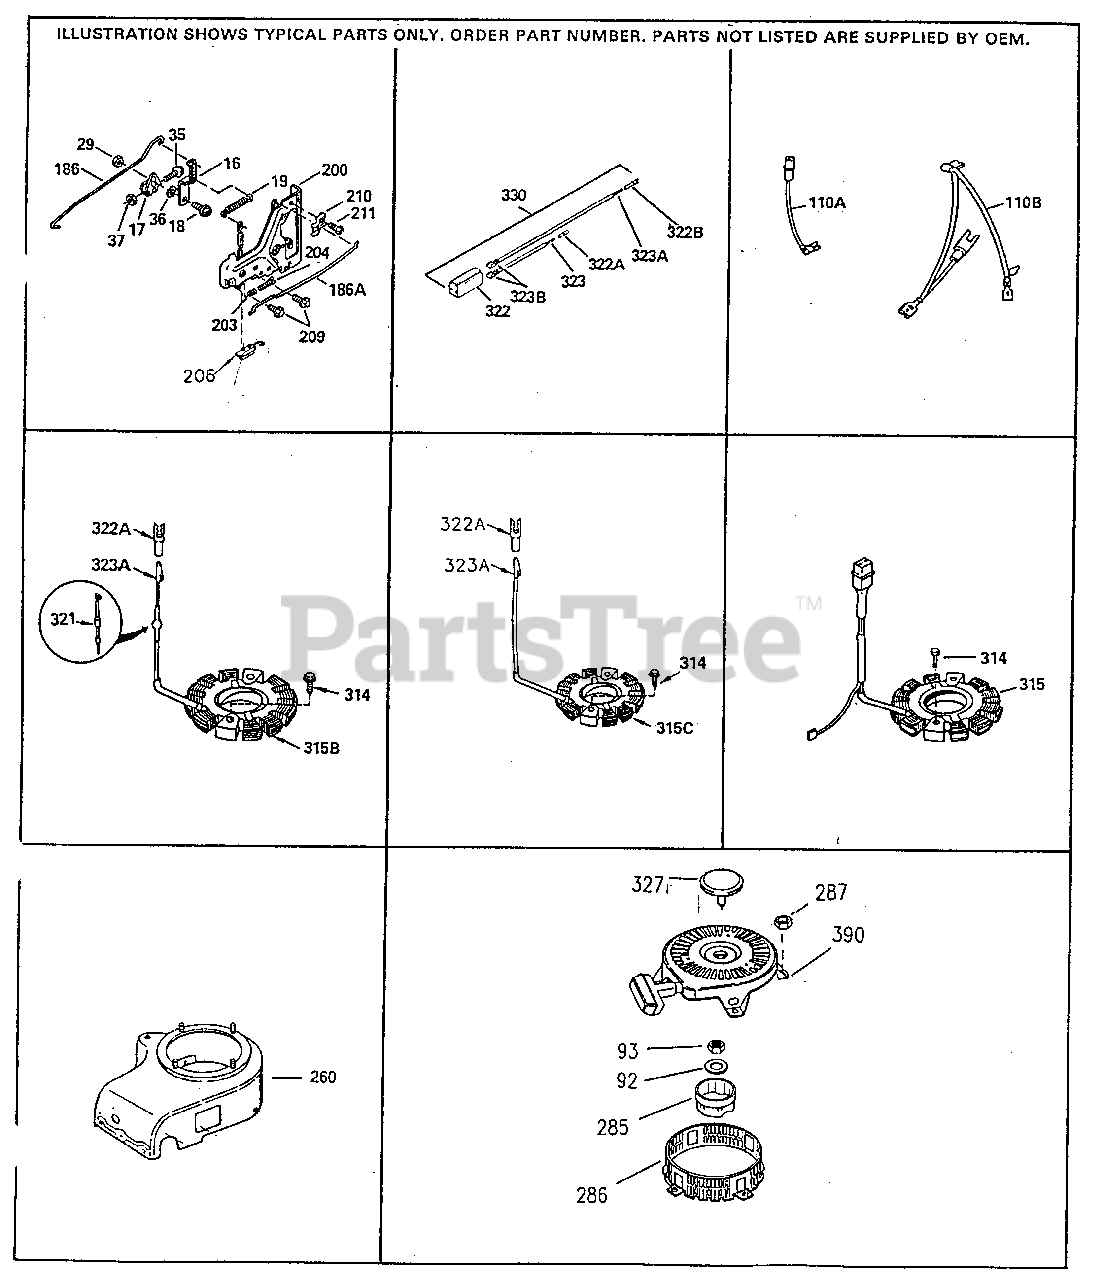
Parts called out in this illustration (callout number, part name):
16	Governor Lever (Incl. 212A)
17	Governor Lever Clamp
18	Screw, 8-32 x 5/16"
19	Extension Spring
28	Lock Nut, 8-32
35	Screw, 10-32 x 3/4"
36	Lock Washer #8
37	Lock Nut, 10-32
92	Lock Washer
93	Flywheel Nut
186	Governor Link
186A	Choke Link
200	Control Bracket (Incl. 203 & 204)
203	Compression Spring
204	Screw, 6-32 x 21/32"
209	Screw, 10-32 x 7/16"
210	Conduit Clip
211	Screw, 10-32 x 3/8"
238	Screw, 10-32 x 5-1/4"
245A	Pre-Cleaner Air Filter also available in Packaged Part #740015B
260	Blower Housing
261	Screw, T-30, 1/4-20 x 1/2"
262A	Screw, 5/16-24 x 25/32"
264A	Screw, T-30, 1/4-20 x 1/2"
286	Cup & Screen
314	Screw, 1/4-20 x 3/4"
315	Alternator Coil (3/5 Split) Incl. 321 , 322,323
322	Connector Body
323	Terminal
337	Deflector
